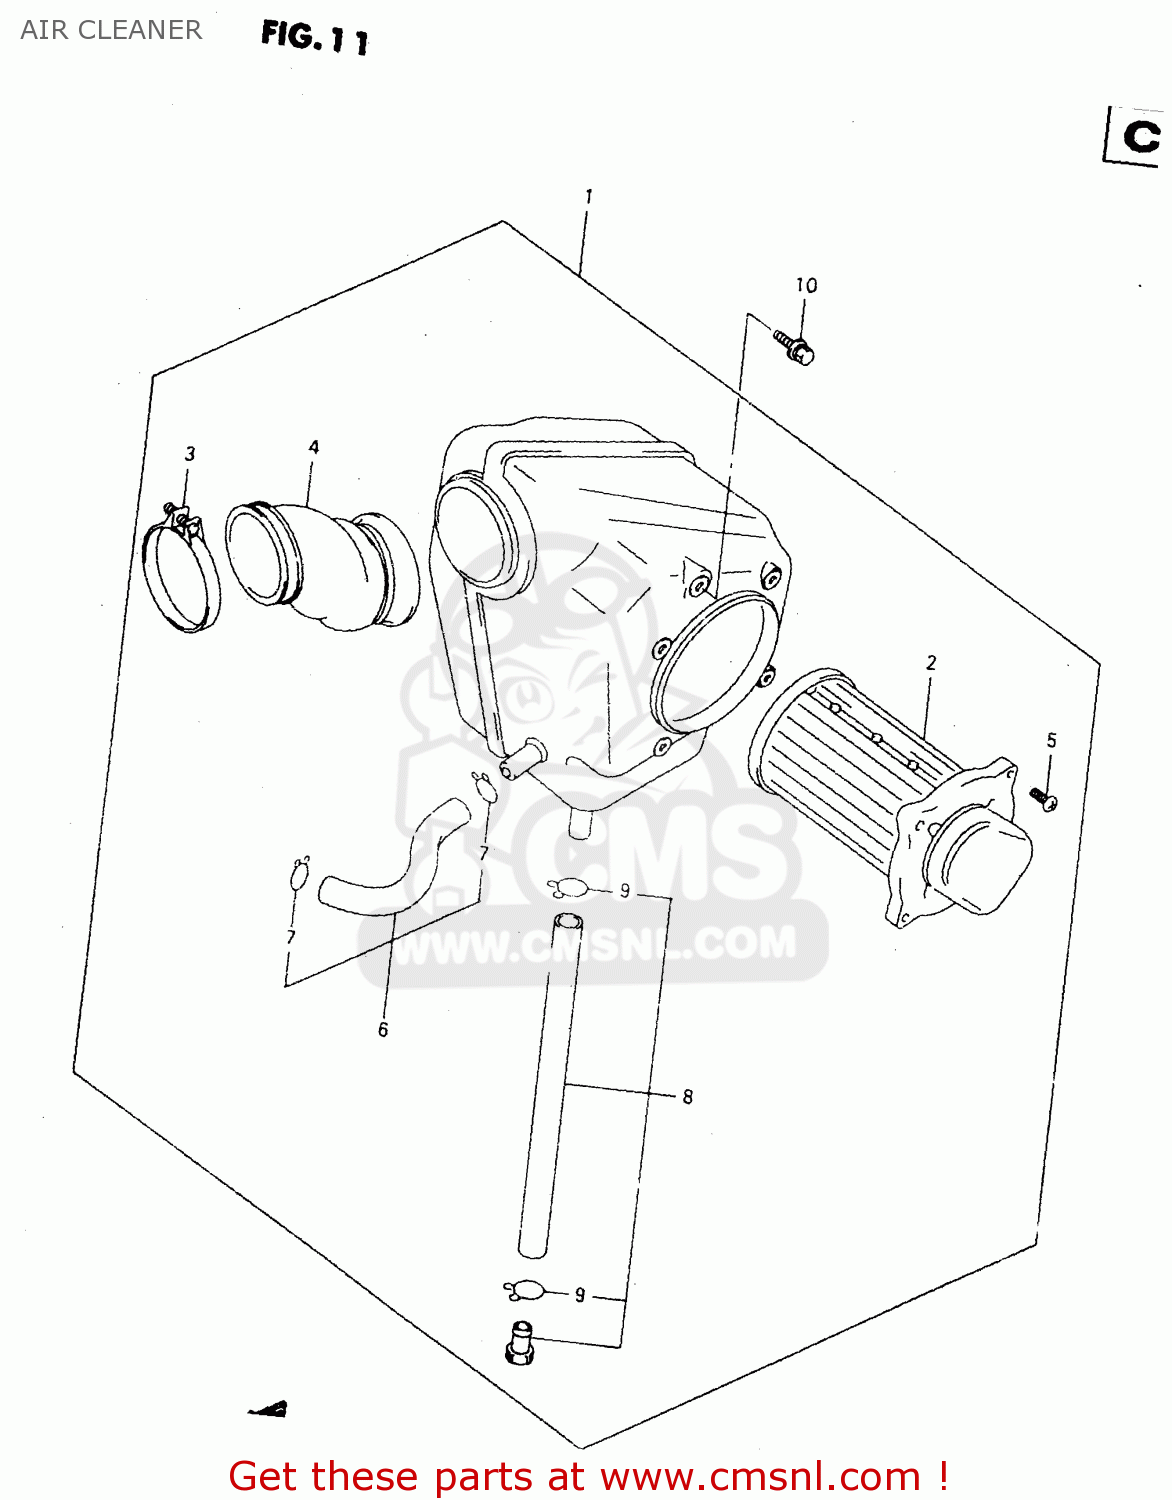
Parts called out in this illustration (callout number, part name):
1	CLEANER ASSY,AIR
2	FILTER,AIR CLEANER
3	CLAMP
4	TUBE,OUTLET
5	SCREW
6	TUBE,BREATHER
7	CLIP
8	TUBE,DRAIN
9	CLIP
10	BOLT
